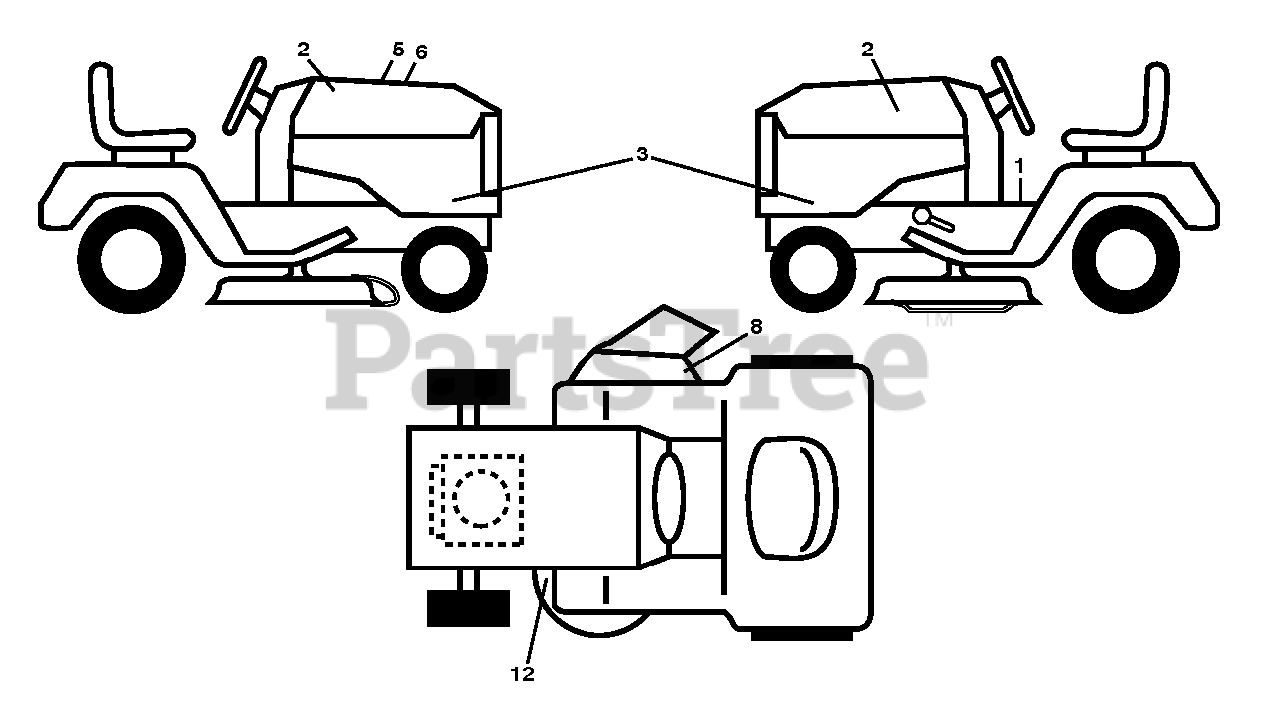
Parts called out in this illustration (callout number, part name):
1	DECAL.FENDER.WARNING.ENGLISH
2	DECAL.BADGE.170MM.TEXTLOGO.
3	Decal, Side Panel GT2 Set YTH20K42
5	DECAL.WARNING.CUST.RESP.E85.
6	Decal, Replacement Kohler KT7 TLW 42C K46L
8	DECAL, DECK DEFLECTOR, WARNING
12	DECAL.V-BELT.SCH.42/46"MEC/ELE
